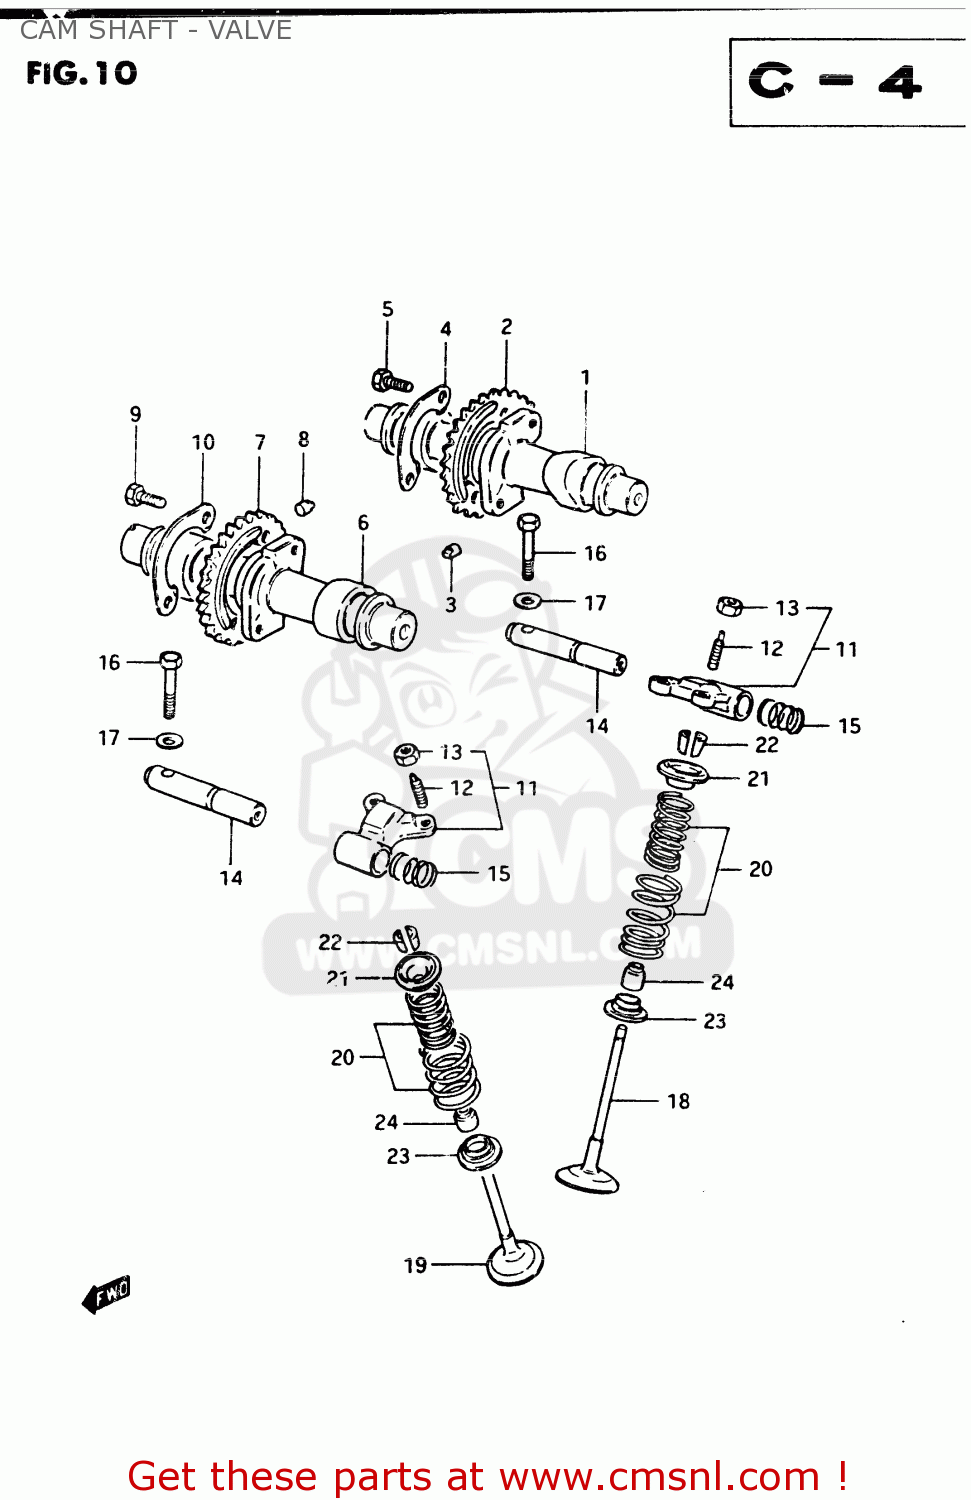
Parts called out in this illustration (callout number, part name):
1	CAM SHAFT, INTAKE
2	SPROCKET (NT:30)
3	PIN,SPROCKET
4	BOLT(6X12.5)
5	WASHER,CAM CHAIN SPROCKET
6	CAMSHAFT,EXHAUST
7	SPROCKET (NT:30)
8	PIN,SPROCKET
9	BOLT(6X12.5)
10	WASHER,CAM CHAIN SPROCKET
11	ARM,VALVE ROCKER
12	SCREW,TAPPET ADJUSTING
13	NUT,ADJUSTING
14	SHAFT,VALVE ROCKER ARM
15	SPRING
16	BOLT
17	WASHER
18	VALVE,INTAKE
19	VALVE,EXHAUST
20	SPRING SET,VALVE
21	RETAINER,VALVE SPRING
22	COTTER VALVE
23	SEAT,VALVE SPRING
24	OIL SEAL
